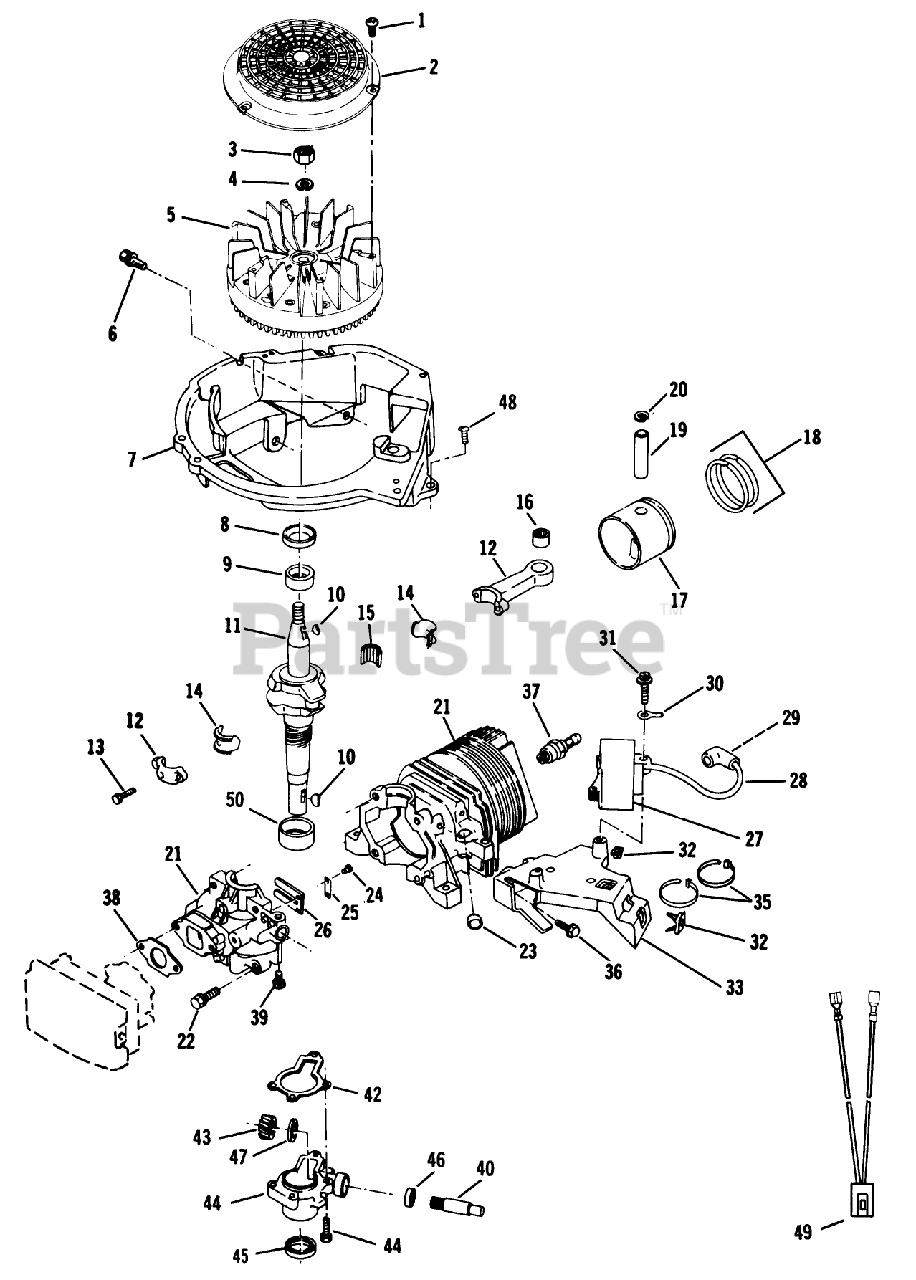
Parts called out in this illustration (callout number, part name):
1	SCREW F
2	SCREEN F'WHEEL S
3	NUT
6	SCREW-SEMS
9	BEARING V
10	KEY
13	SCREW-HSH
14	LINER ASM
16	BEARING AY F
20	RING-RETAINING
22	SCREW S
23	PLUG-CORE VF
25	PLATE-BACKUP, REED
28	HT LEAD&COVER XEV
30	TERMINAL S
32	NUT-CLIP
38	GASKET CARB S
42	GASKET S
43	GEAR, DR SHAFT S
45	SEAL-OIL
46	SEAL S
47	THRUST WASHER
48	SCREW F
50	BEARING S
